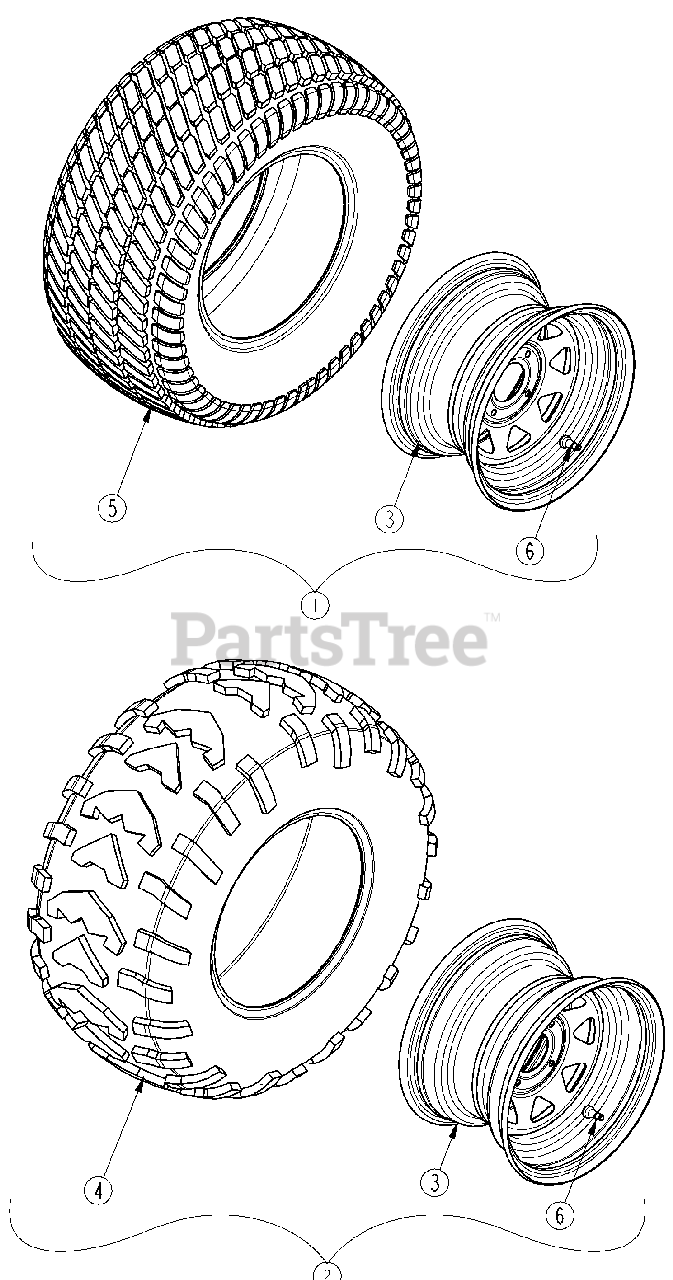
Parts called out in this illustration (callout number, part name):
1	TIRE/RIM REAR TURF 23-10.5-12
2	AT TIRE/RIM BLACK RIGHT REAR
2	AT TIRE/RIM BLACK LEFT REAR
2	AT TIRE/RIM BLACK RIGHT FRONT
2	AT TIRE/RIM BLACK LEFT FRONT
3	RIM 12X8.5 4-4 BOLT BLACK
4	TIRE 25 X 11 X 12 AT489
5	TIRE TURF 23-10.5-12
6	VALVE STEM TR415 X. 625 X 1 1/4 LG
